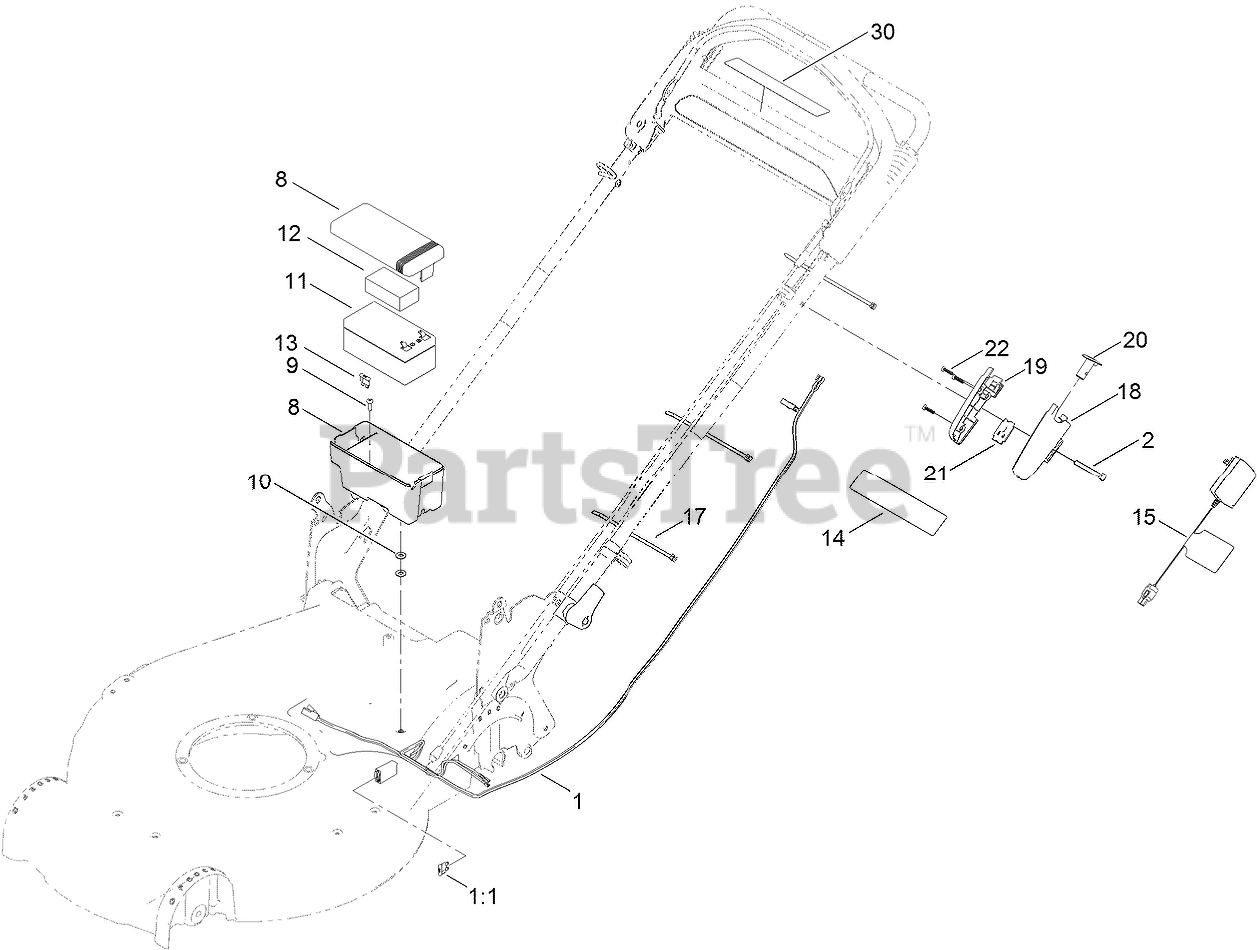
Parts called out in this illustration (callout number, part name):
1	HARNESS-WIRE
1:1	FUSE-40 AMP
2	SCREW-HH
8	BATTERY BOX ASM
9	SCREW-THD FORM
10	WASHER-FLAT
11	BATTERY-WET
12	FOAM-BATTERY, TOP
13	FUSE-40 AMP
14	DECAL-BATTERY CHARGING
15	CHARGER, BATTERY (12V, CE)
17	TIE-CABLE
18	HOUSING-SWITCH, LH
19	HOUSING-SWITCH, RH
20	BUTTON-SWITCH
21	SWITCH-PUSH BUTTON
22	SCREW-PPH
30	DECAL-BUTTON, PUSH
